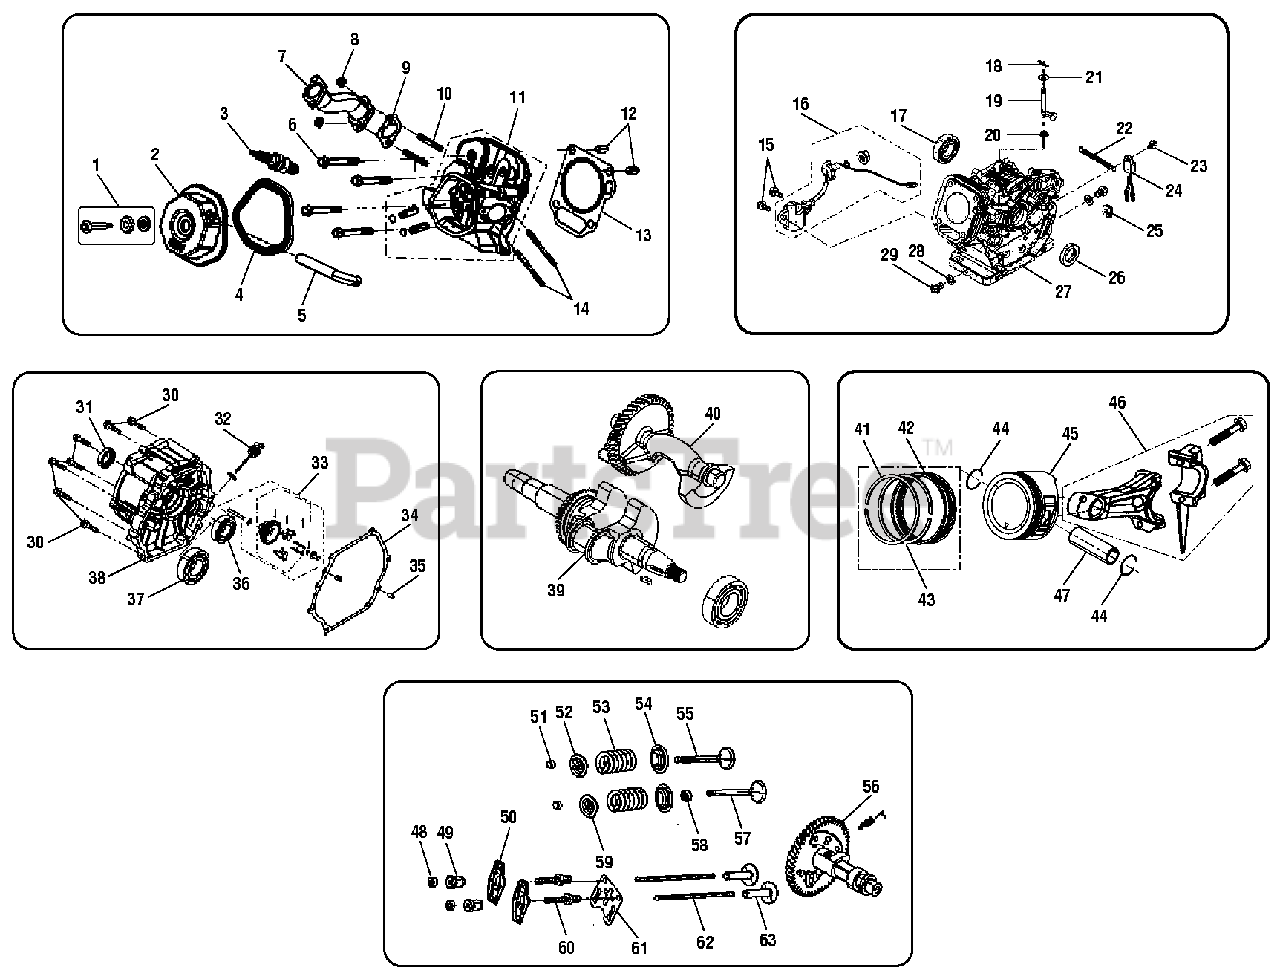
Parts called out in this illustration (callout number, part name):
2	Cylinder Head Cover
3	Spark Plug
4	Cylinder Head Cover Gasket
5	Breather Tube
7	Exhaust Pipe
9	Exhaust Outlet Gasket
10	Threaded Stud
11	Cylinder Head Assembly
13	Cylinder Head Gasket
14	Threaded Stud
16	Engine Oil Sensor
17	Ball Bearing
18	Pin
19	Governor Arm
24	Oil Protector
27	Crankcase Assembly
32	Oil Dipstick Assembly
33	Governor Gear Assembly
34	Crankcase Gasket
36	Ball Bearing
37	Ball Bearing
38	Crankcase Cover
39	Crankshaft Assembly
40	Balancing Shaft
41	The First Ring
42	Oil Ring Kit
43	The Second Ring
44	Piston Pin Clip
46	Connecting Rod
48	Valve Lock Nut
49	Valve Adjusting Nut
50	Valve Rocker
51	Valve Rotator
52	Exhaust Valve Retainer
53	Valve Spring
54	Valve Spring Retainer
55	Exhaust Valve
56	Camshaft Assembly
57	Intake Valve
59	Valve Spring Seat
60	Valve Adjusting Bolt
61	Stop Plate Assembly
62	Valve Lifter Assembly
